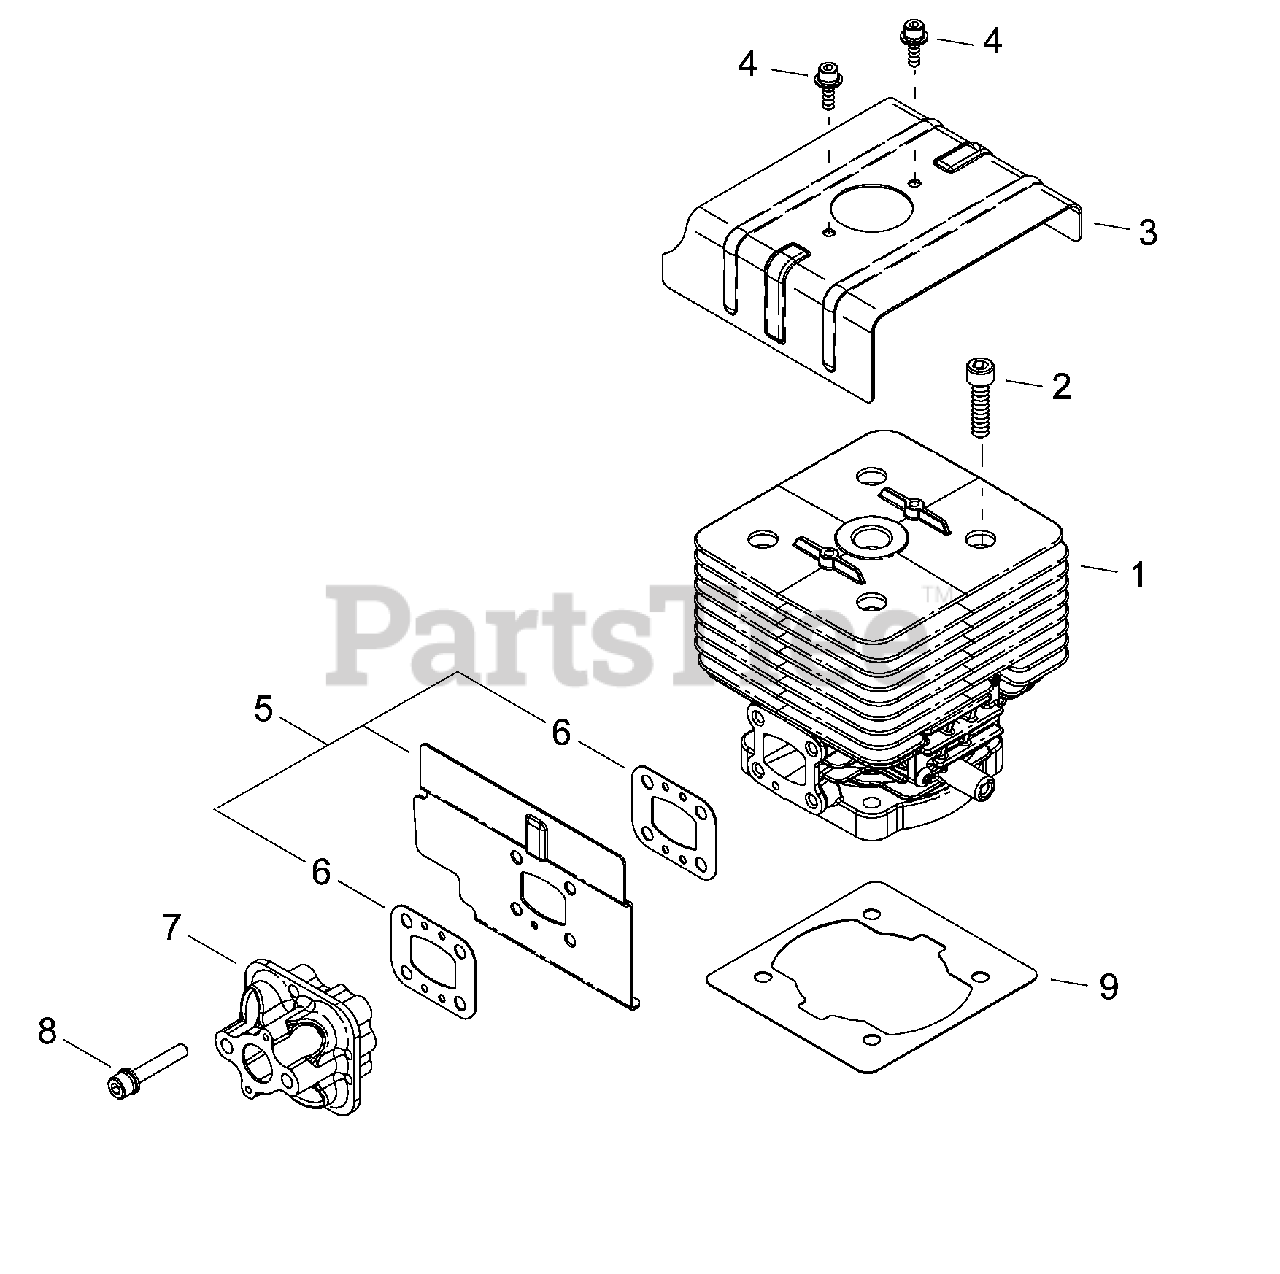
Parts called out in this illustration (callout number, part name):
1	CYLINDER ASSY
2	SCREW - 6X25
3	SHIELD, CYLINDER
4	SCREW - 4X12
5	INTAKE SHIELD ASSY
6	GASKET, INTAKE
7	INSULATOR
8	SCREW - 5X30
9	GASKET, CYLINDER
